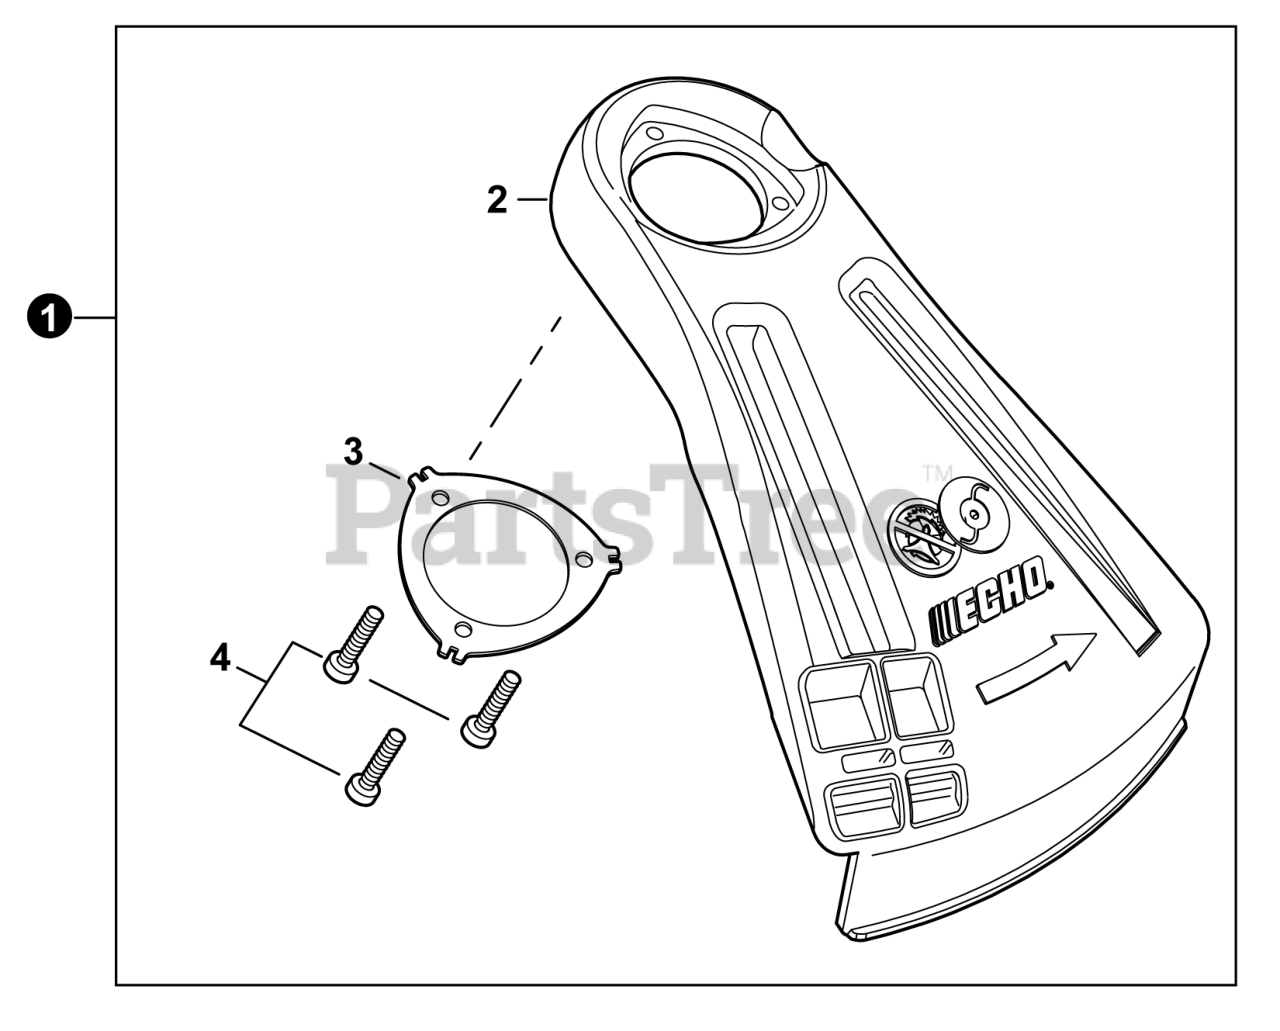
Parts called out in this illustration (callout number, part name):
1	SHIELD KIT, DEBRIS
2	SHIELD, DEBRIS PLASTIC
3	PLATE, SHIELD
4	BOLT, TORX 5x16
